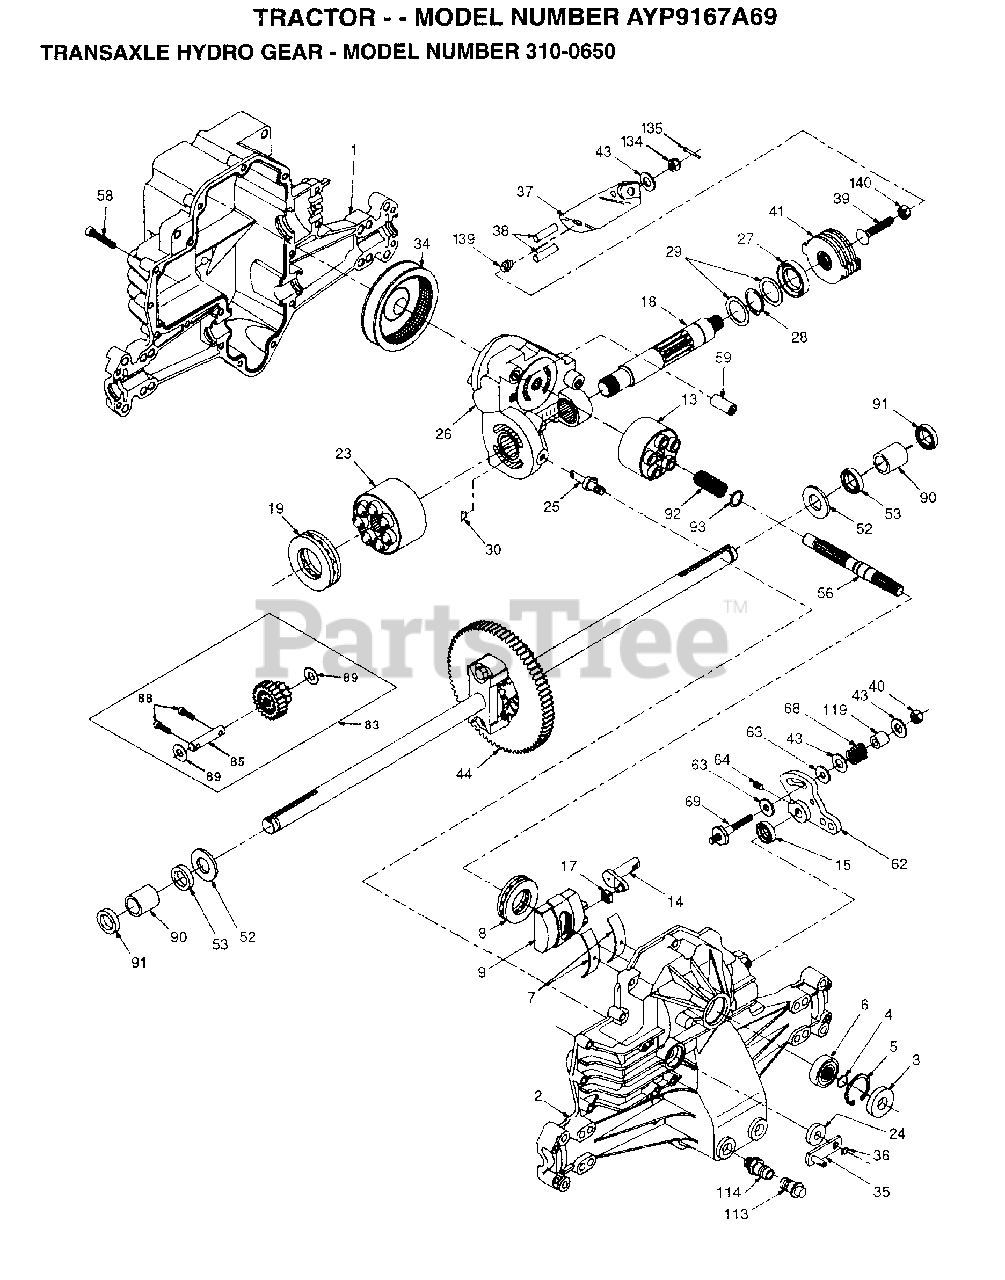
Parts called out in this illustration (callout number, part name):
1	HOUSING.L.50074RM
2	HOUSING.UP.70125
3	SEAL.9008000-0128
4	RING.RET.2003016.
5	RING.RET.2003052.
6	BEARING.(50552)42X68X16
7	CRADLE- 2003023.
8	BEARING.THU.50551
9	SWASHPLT.2003087.
13	BLOCK.CLYN.70079.
14	ARM.TRUN.2003005.
15	SEAL.9008000-0126
17	GUIDE.2000015.
18	SHAFT.MOTOR.50449
19	BEARING.THU.50552
23	BLOCK.CYLIN.70082
24	SEAL.LIP.45074
25	ACTUATOR.2003555
26	KIT.CEN.SEC.70250
27	SEAL.LIP.45075
28	RING RETAIN 50007
29	WASHER.44872
34	ELEMENT.OIL.44964
35	ARM.BYPASS.50270
36	RING.RETAIN.44870
37	ARM.ACTUAT.23710
38	PIN.ACTUAT.44891
39	BOLT.50316
40	NUT.LOCK.HX.50317
41	KIT.BRAKE.70135
43	WASHER HYD 44130
44	DIFFRENTIAL.70226
52	WASHER.HYD.44875
53	SEAL.HYDRO.45076
56	SHAFT.INPUT.50005
58	BOLT.1/4-20.44876
59	PIN.HYDRO.50002
62	ARM.CONTROL.50254
63	PUCK.DAMPER.50281
64	SCREW.SET.50018.
68	SPRING.HYD.50277
69	STUD.5/16-24.DANA
83	JACKSHAFT/PINION GEAR.70132
85	PIN.SHAFT 50559
88	SCREW.CAP.50154.
89	WASHER.HYD.50132
90	BEARING.SLV.50118
91	SEAL.WIPER.50941
92	SPRING.2003014.
93	WASHER.2003017
113	CAP.VENT.70109
114	O-RING.ASM.70110
119	SPACER.HYD.50278
134	NUT.CAS.HYD.44142
135	PIN.COT.HYD.44101
139	SPRING.COMP.50431
140	NUT.HEX.50269
